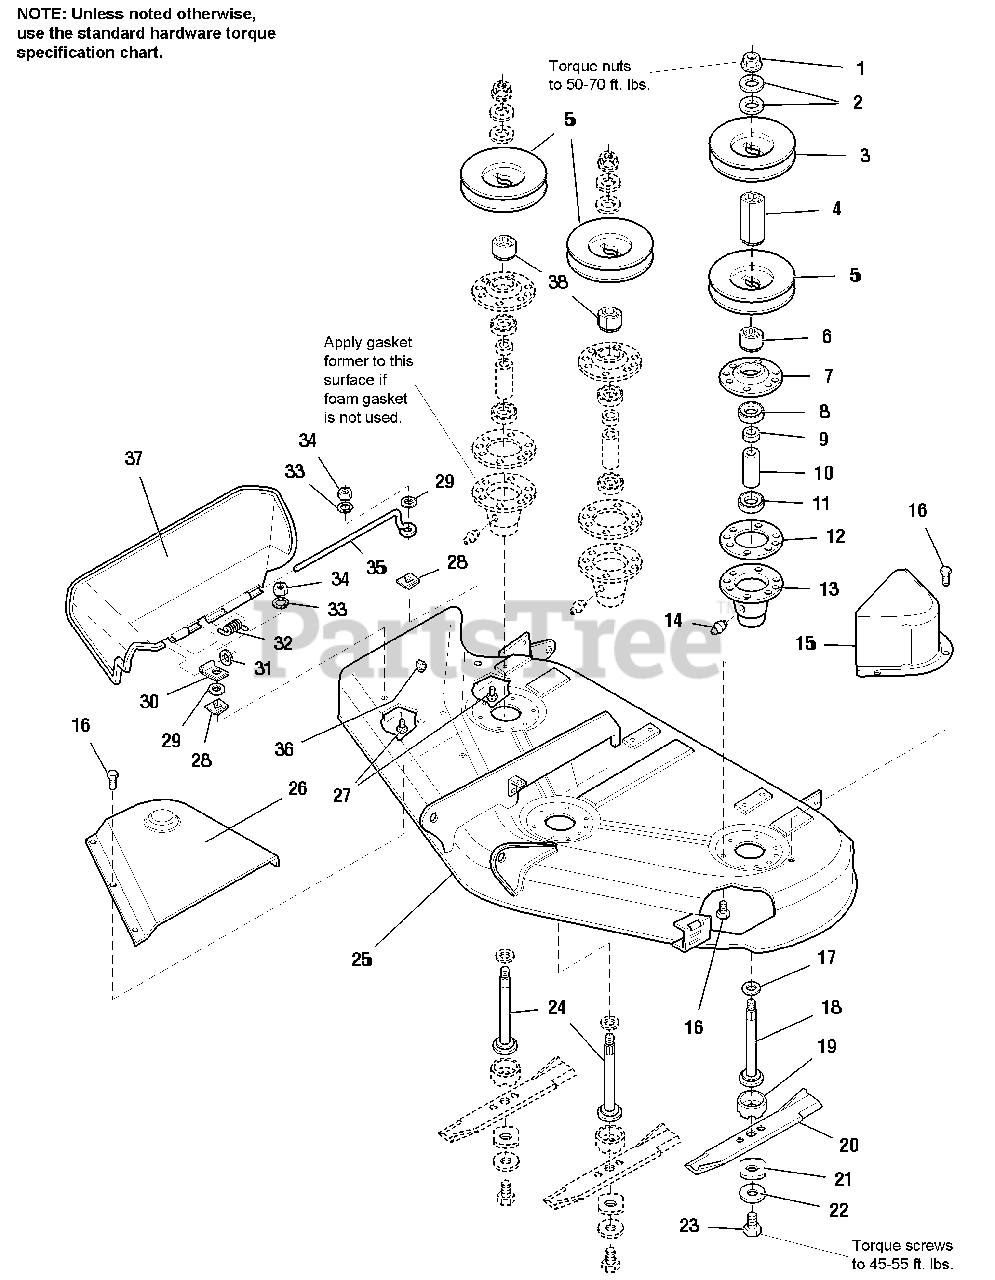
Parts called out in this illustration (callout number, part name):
1	NUT, Hex Flange, 9/16-8
2	WASHER, Belleville
4	HUB, Double Pulley, LH Arbor
6	HUB, Double Pulley, LH Arbor
7	COVER, Arbor Housing
9	SPACER, Bearing Sleeve
12	GASKET, Foam
13	HOUSING ASSEMBLY, Arbor Bottom, w/Lube Fitting
14	FITTING, Grease
15	COVER, Arbor
16	CAPSCREW, Taptite, 5/16-18 x 3/4 (Qty. 25 used on 44" Deck)
18	SHAFT, Arbor (LH)
19	SHIELD, Grass, Lower
20	BLADE, Mower, 16-1/8
20	BLADE, Mower, 18-1/8", 50" Deck
21	WASHER, Hex
22	WASHER, Spring
23	CAPSCREW, Hex, Head, 7/16-14 x 1-1/4
24	SHAFT, Arbor (Center & RH)
25	MOWER HOUSING ASSEMBLY, 44" Mower (Orange)
25	MOWER HOUSING ASSEMBLY, 50" Mower (Orange)
25	MOWER HOUSING ASSEMBLY, 44" Mower (Charcoal Grey)
25	MOWER HOUSING ASSEMBLY, 50" Mower (Charcoal Grey)
26	COVER, Arbor
27	CARRIAGE BOLT, 1/4-20 x 7/8
28	NUT, Push
29	WASHER, Plain
31	WASHER, 5/16
34	NUT, Hex, 1/4-20 UNC ESNA
35	ROD, Deflector, Front
37	DEFLECTOR, Plastic
38	HUB, Pulley, RH & Center Arbor
